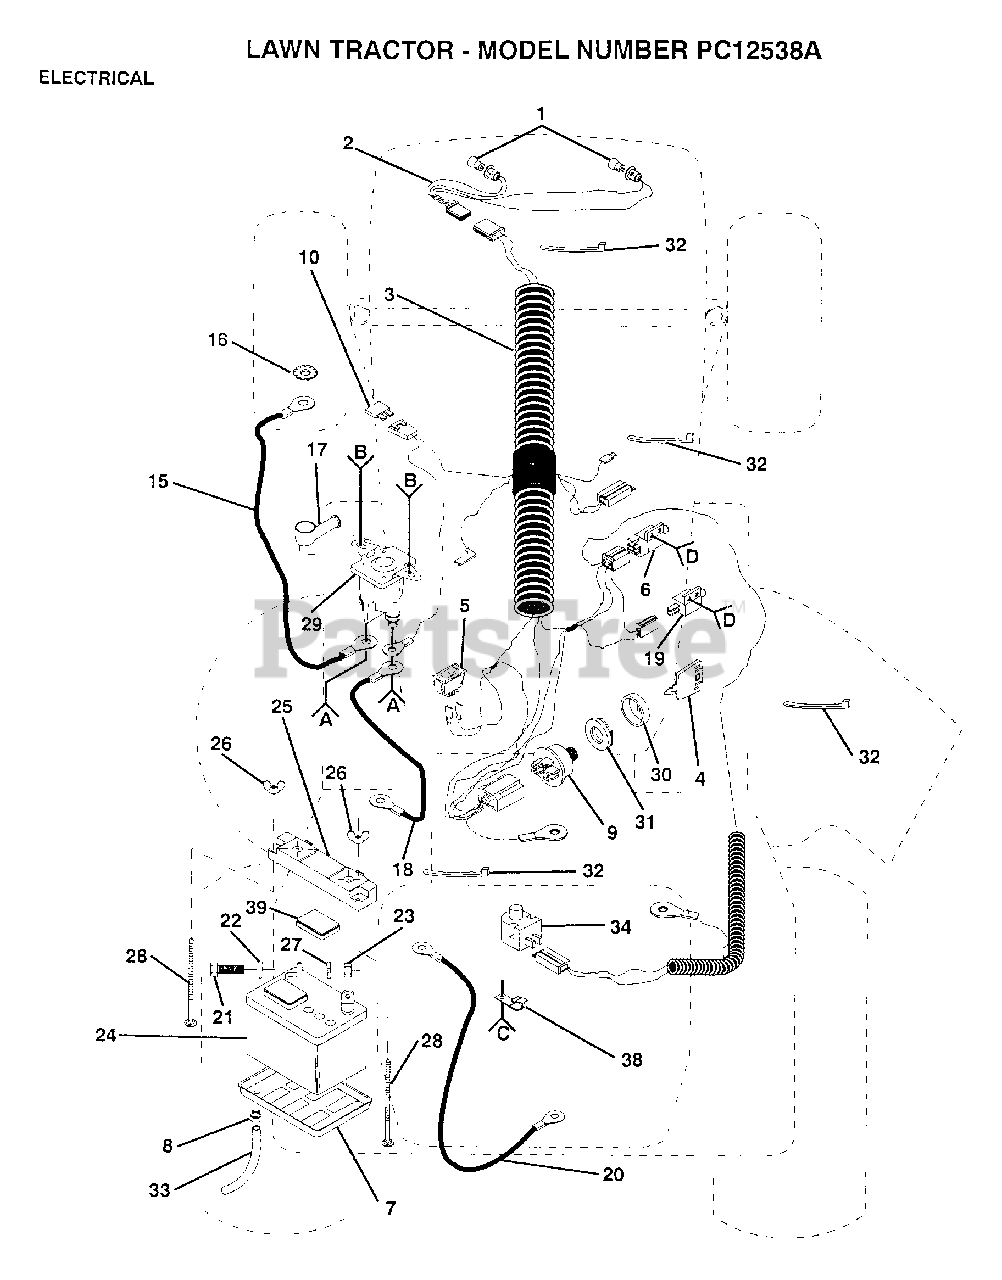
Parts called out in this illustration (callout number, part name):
2	HARNESS T
3	"HARNESS,WIRING"
5	SWITCH LT
6	SWITCH-INTER. GT
7	"TRAY T, BATTERY"
8	HOSE CLAMP T
10	FUSE HYT
18	STARTER CABLE GT
19	SWITCH INTERLOCKT
21	BOLT LT
22	WASHER
27	LOCKWASHER
28	BOLT
32	WIRE TIE
34	SWITCH SEAT
39	"CAP,BATTERY "
